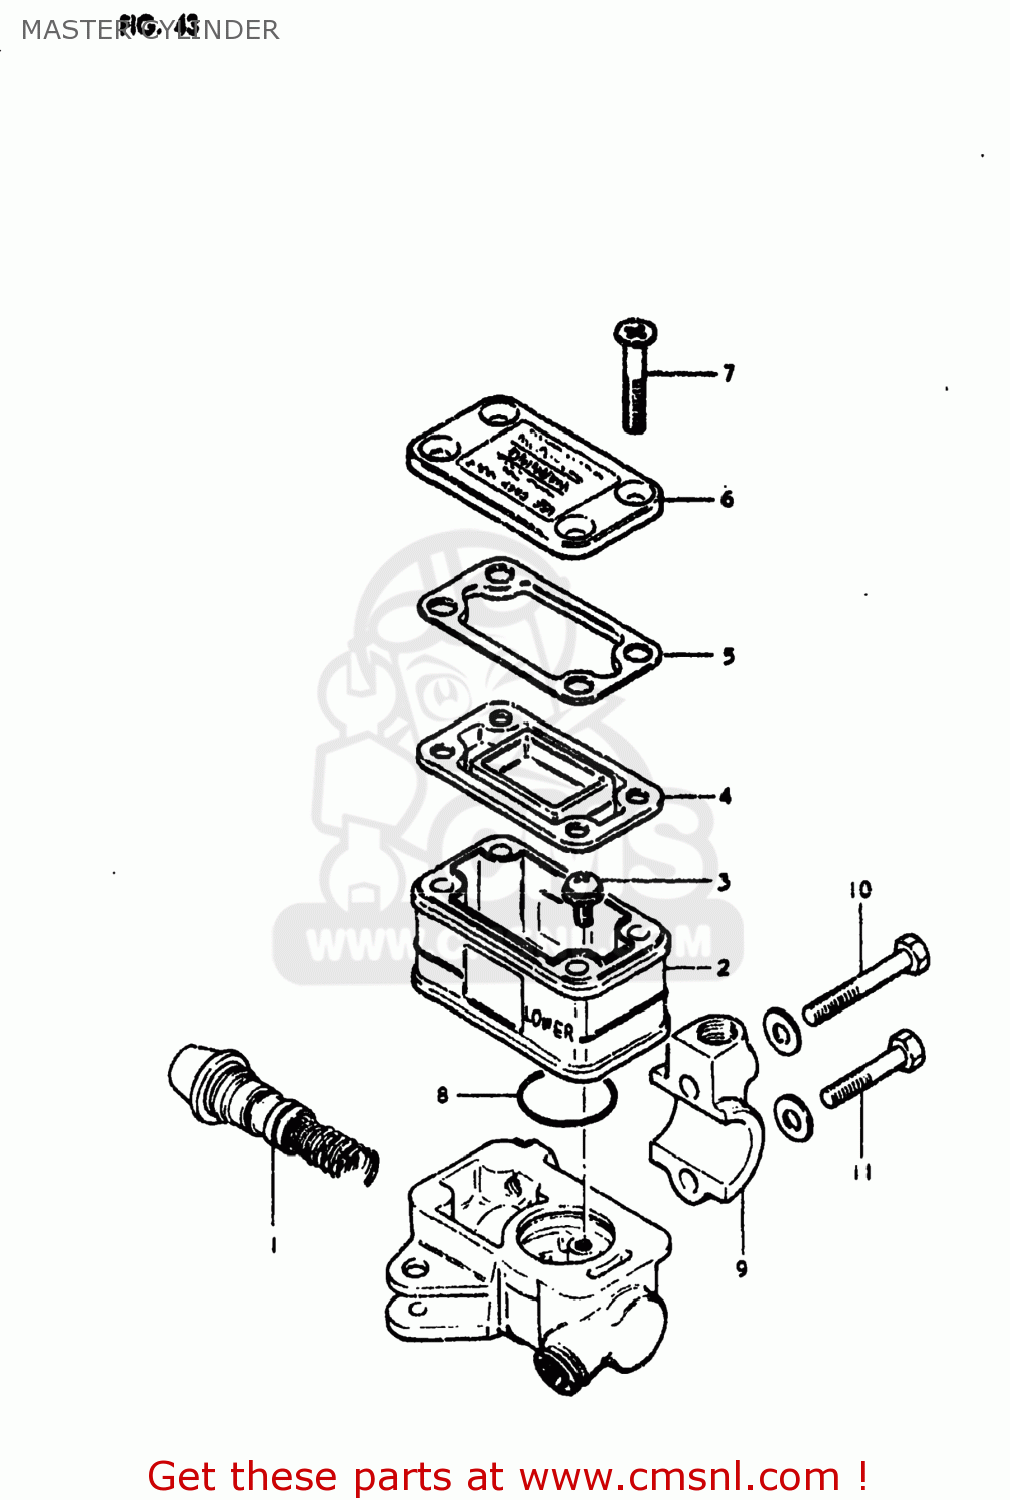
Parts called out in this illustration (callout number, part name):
1	PISTON & CUP SET
2	RESERVOIR
3	SCREW,MASTER C
4	DIAPHRAGM
5	PLATE,DIAPHRAGM
6	CAP
7	SCREW
8	O RING
9	HOLDER
10	BOLT,MASTER CYLINDER H
11	BOLT,MASTER CYLINDER H
